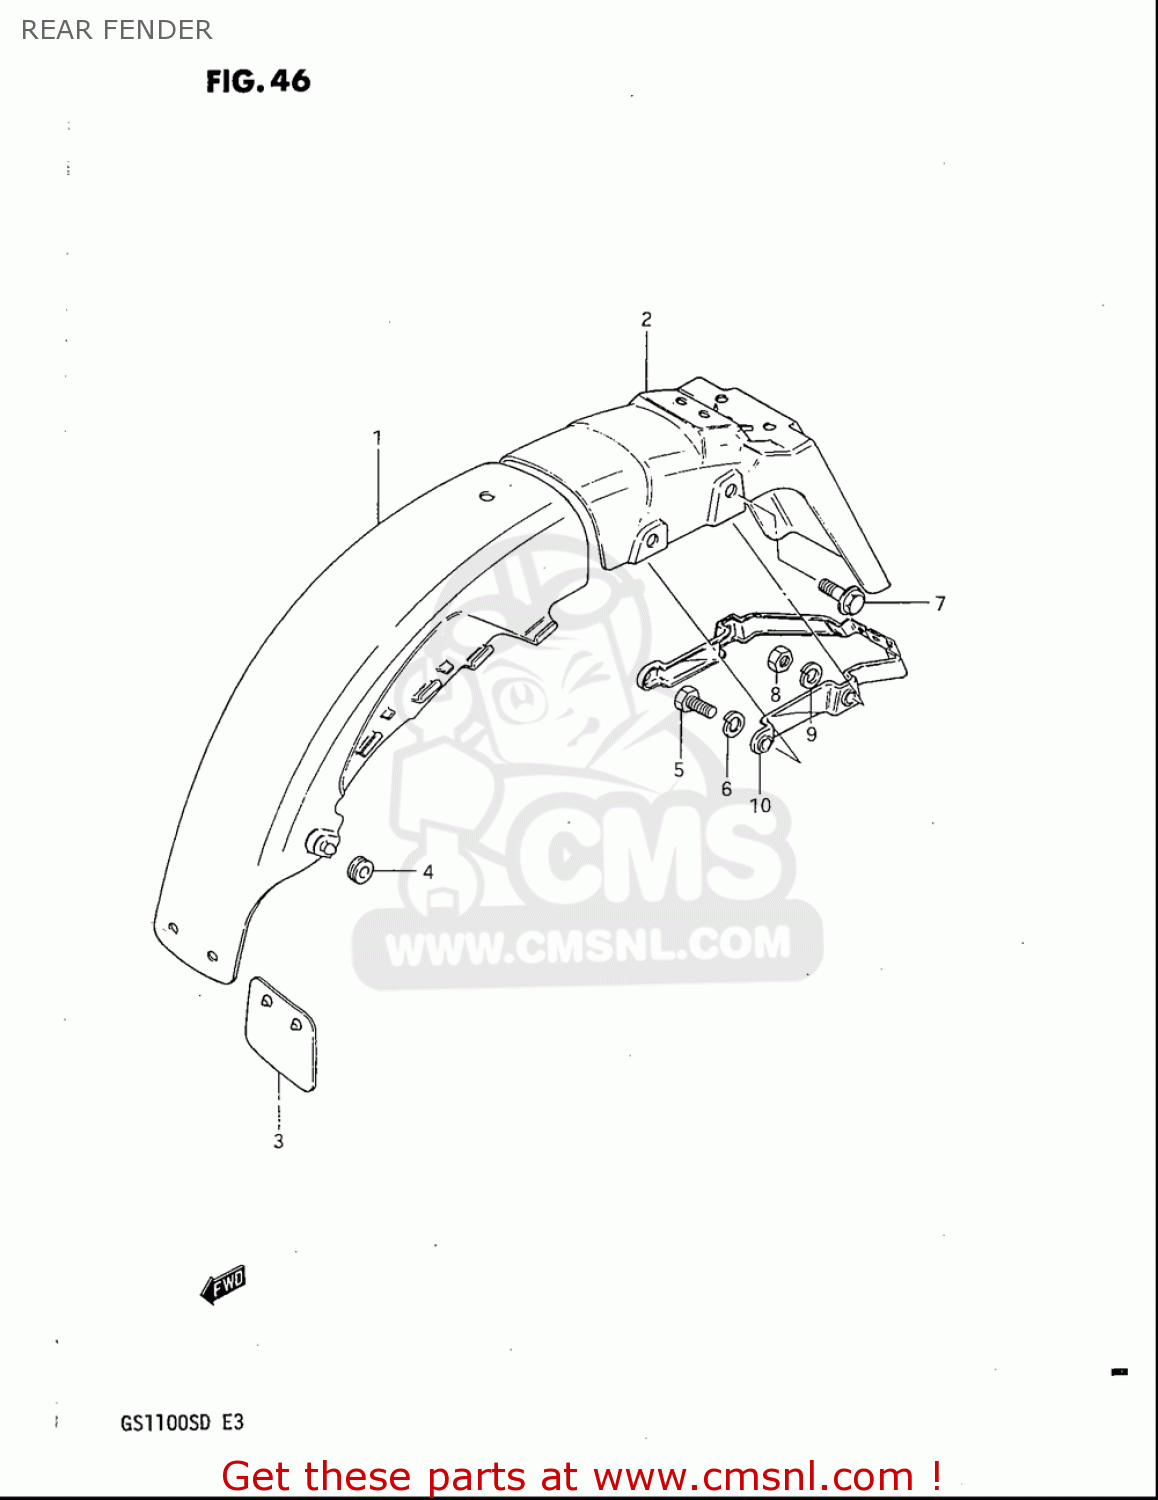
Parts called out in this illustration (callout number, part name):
1	BODY,RR FENDER FR
2	BODY,RR FENDER RR
3	GUIDE,RR FENDER MUD
4	CUSHION
5	BOLT
6	WASHER,LOCK
7	BOLT
8	NUT
9	WASHER,LOCK
10	REINFORCEMENT,RR FENDER
